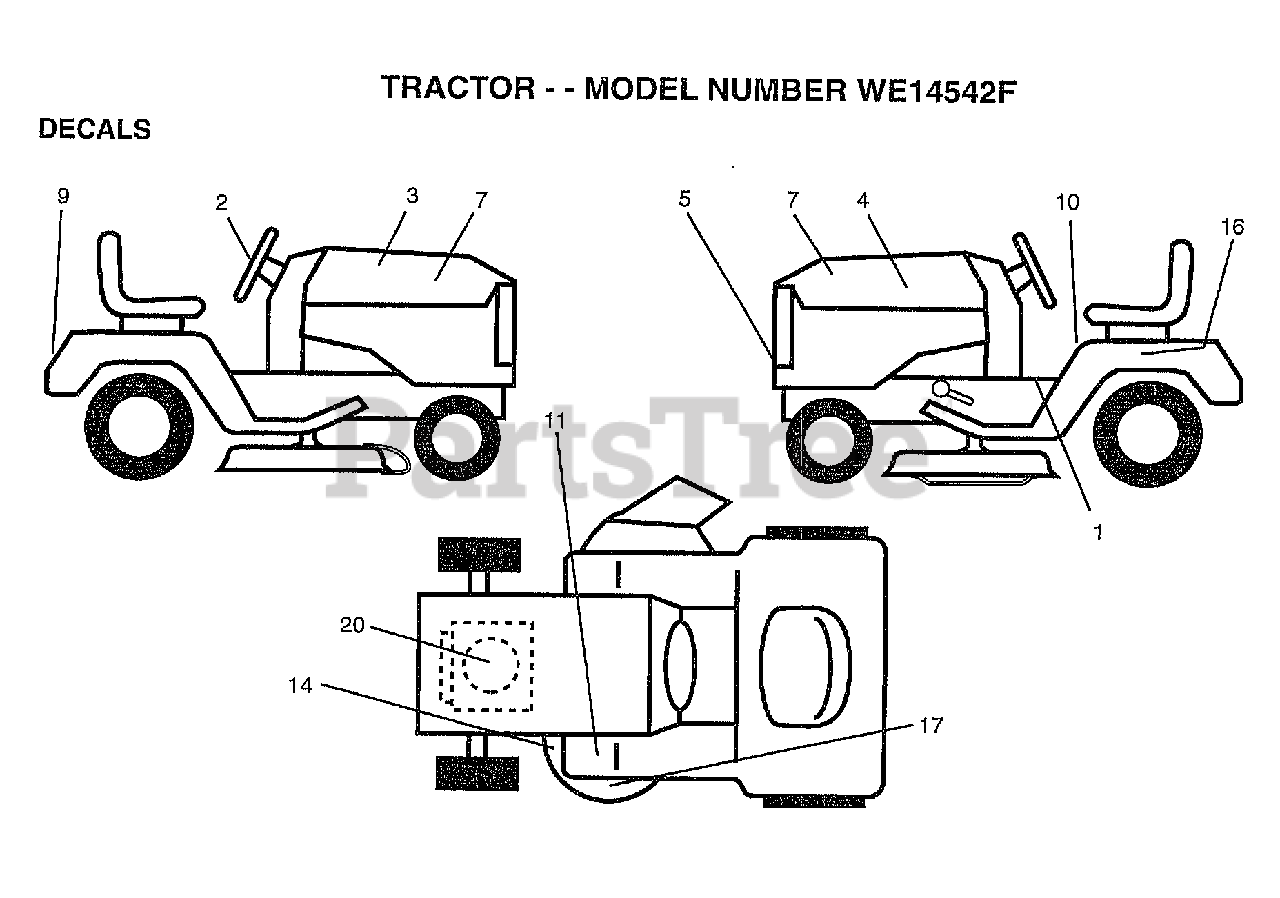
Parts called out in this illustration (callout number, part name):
1	"DECAL DASH,OPER."
2	DECAL, INS STRG WH
3	DECAL.HOOD.RH.
4	DECAL.HOOD.LH
5	DECAL, GRILLE LENS
7	DECAL PANEL SIDE
9	DECAL.FENDER.LOGO
10	"DECAL DANGER,FEND"
14	"DECAL-SCHEM,BELT"
16	DECAL.BATRY.3-3908
17	DECAL, DECK GRASSEATER
20	DECAL, ENGINE
